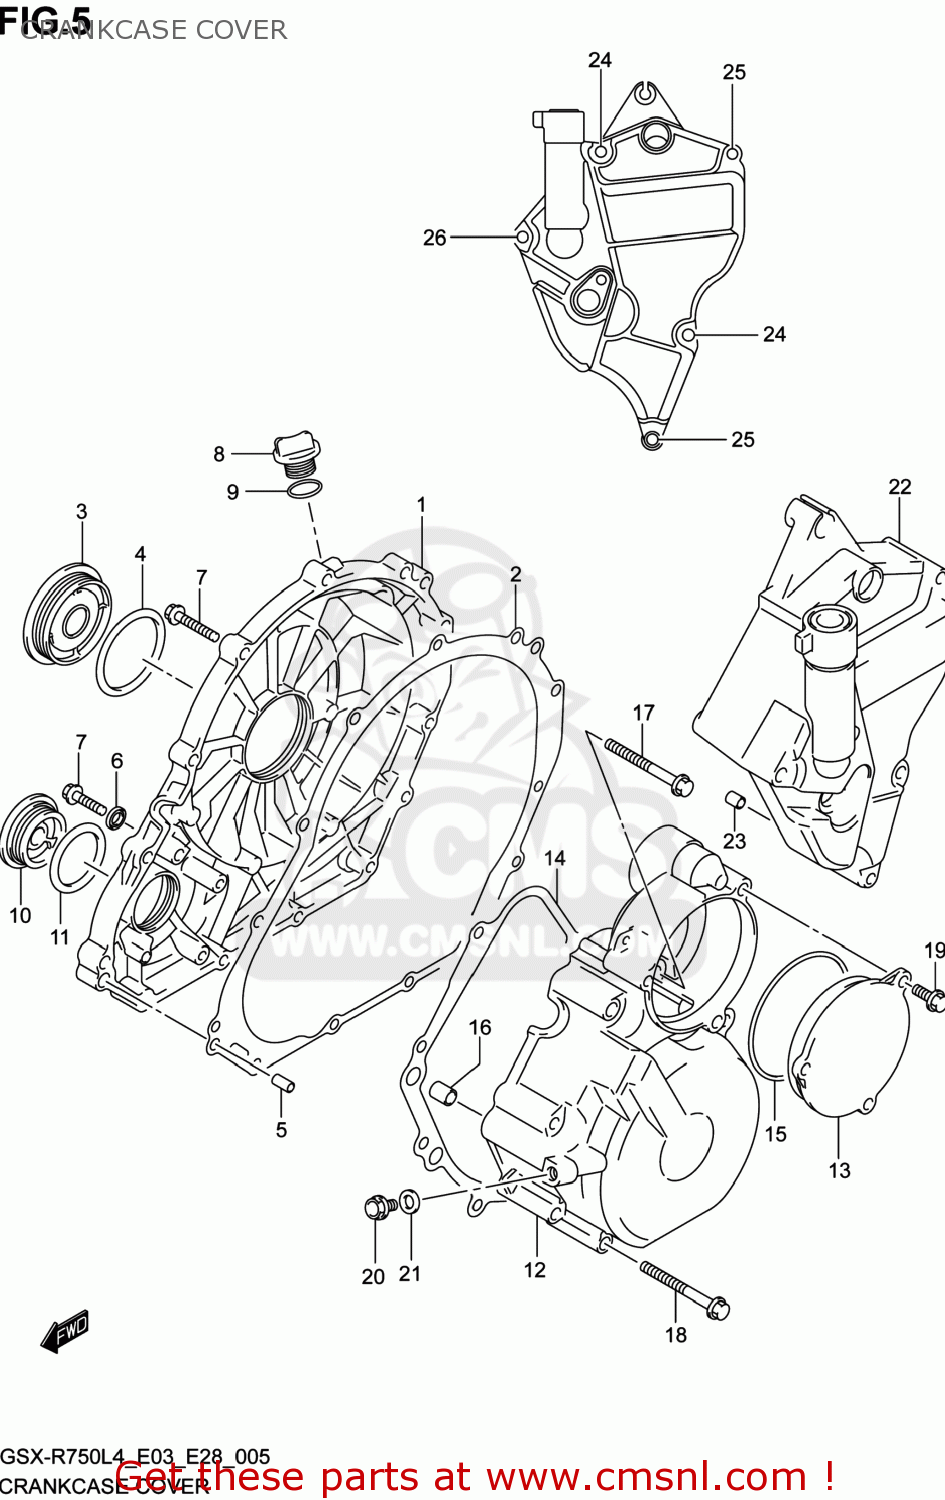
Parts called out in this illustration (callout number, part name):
1	COVER,CLUTCH
2	GASKET,CLUTCH COVER (NAS)
3	CAP,CLUTCH RELEASE ADJUST
4	O RING
5	PIN
6	GASKET(5.8X13X1.2) (NAS)
7	BOLT(6X30)
8	PLUG,ENGINE OIL FILLER
9	O RING(D:3.1,ID:16.8)
10	PLUG
11	O RING(D:3.1,ID:32.7)
12	COVER,GENERATOR
13	CAP,STARTER IDLE GEAR
14	GASKET,GENERATOR COVER (NAS)
15	O RING(D:2.6,ID:67.1)
16	PIN
17	BOLT(6X25)
18	BOLT(6X50)
19	BOLT(6X16)
20	BOLT(6X12)
21	GASKET(6.2X13X1.2) (NAS)
22	COVER,ENGINE SPROCKET
23	PIN
24	BOLT(6X45)
25	BOLT(6X65)
26	BOLT(6X75)
